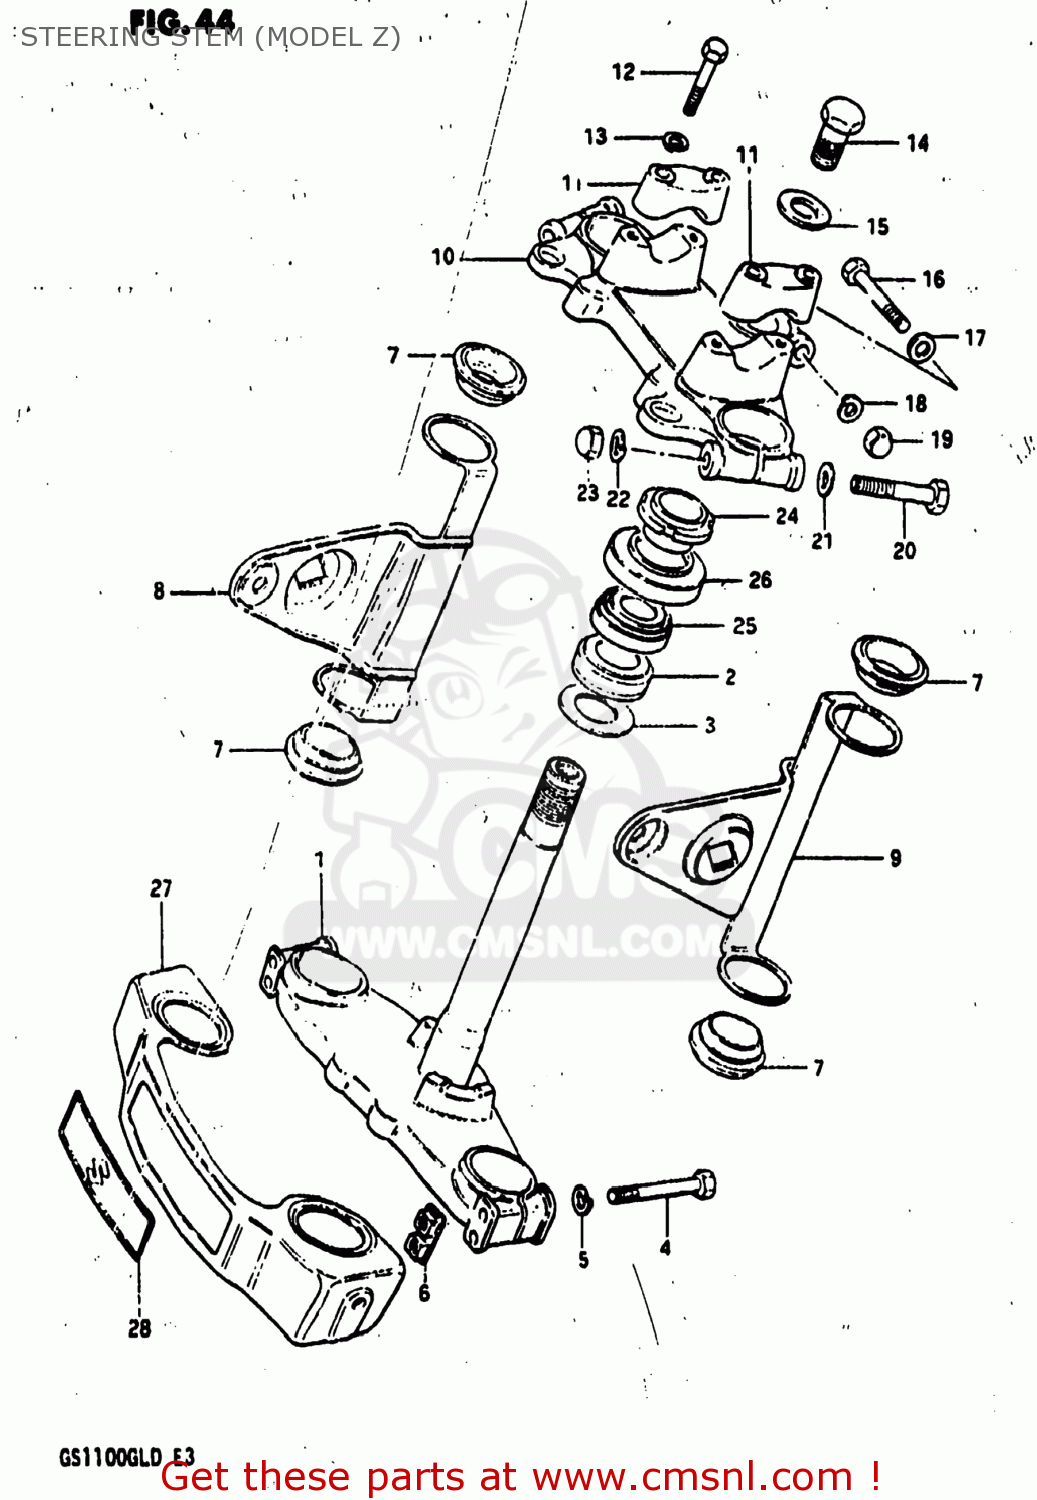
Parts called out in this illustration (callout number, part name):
1	STEM,STEERING
2	BEARING
3	WASHER
4	BOLT 8X55
5	LOCK WASHER
6	NUT,FR FORK INNER TUBE
7	CUSHION,HEADLAMP BRACKET
8	BRACKET,HEADLAMP,RIGHT
9	BRACKET,HEADLAMP,LEFT
10	HEAD,STEERING STEM
11	HOLDER,HANDLE(BLACK)
12	BOLT
13	LOCK WASHER
14	NUT,STEM HEAD
15	WASHER,STEERING STEM
16	BOLT 8X50
17	WASHER
18	WASHER,LOCK,8.
19	NUT
20	BOLT 10X55
21	WASHER
22	LOCK WASHER
23	NUT, LOWER LH
24	NUT,STEERING STEM
25	TAPER,ROLLER BEARING
26	DUST SEAL,STEERING UPR
27	COVER,FRONT FORK
28	EMBLEM,FR FORK COVER
